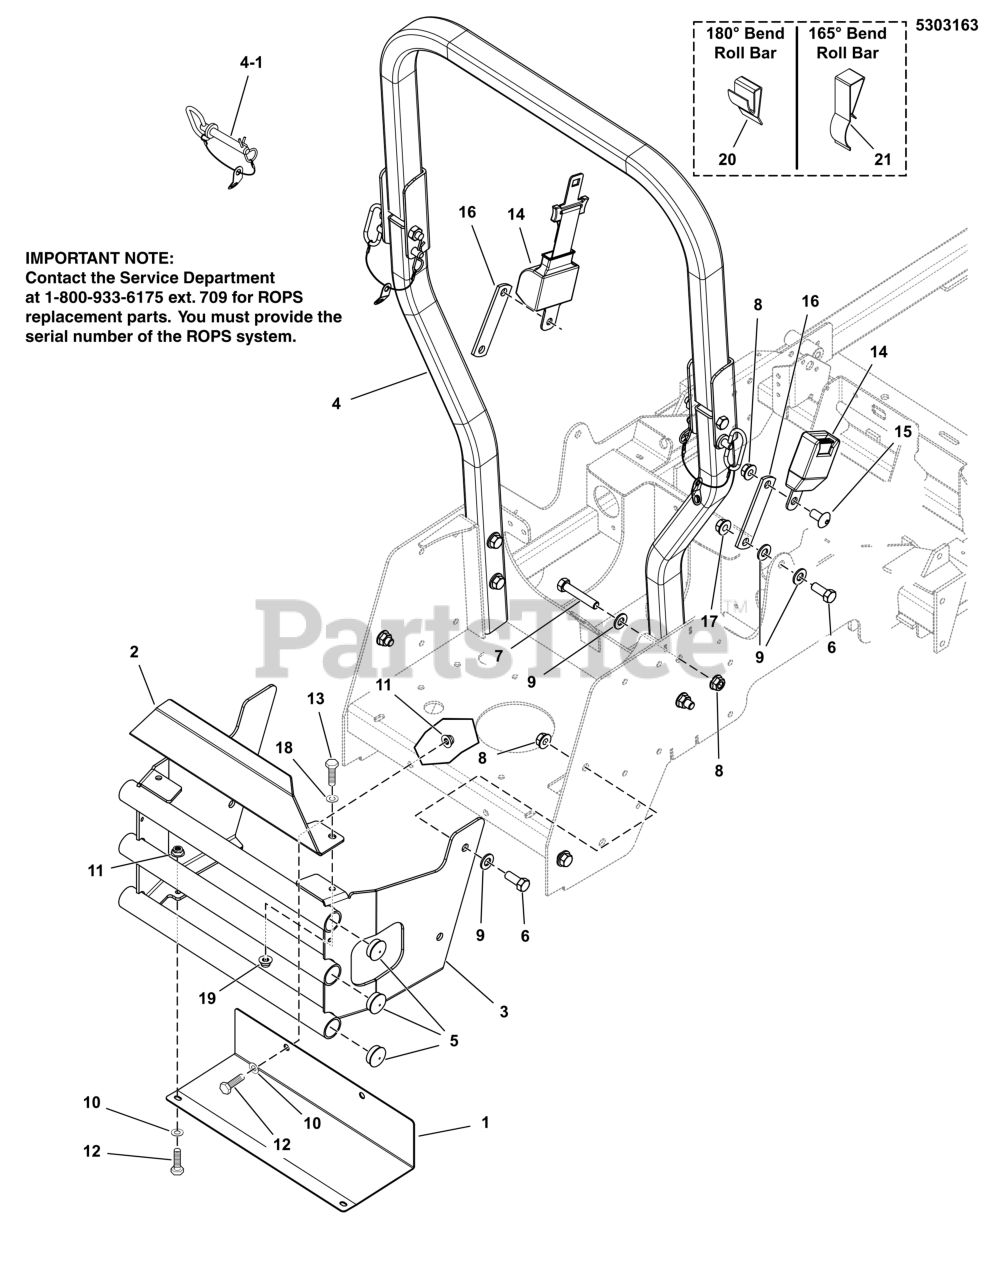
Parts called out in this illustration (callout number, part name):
1	PLATE, HEAT SHIELD, IS700 - BLK
2	PLATE, CARB PROTECTOR - RED
3	WELD, BUMPER - IS700 - RED
4	ROPS (Call 1-800-933-6175 ext. 2193 if replacing a ROPS)
4-1	PIN, HITCH, .50 X 3.2
5	PLUG, PANEL, 1.25 - BLACK
6	BOLT, 1/2-13 X 1-1/4 GD5 CZ
7	BOLT, 1/2-13 X 2-3/4 GD5 CZ
8	NUT, Hex Flange, Nylock, 1/2-13
9	WASHER, 1/2 SAE
10	WASHER, 5/16" SAE
11	NUT, 5/16-18 HEX NYLOCK FLANGE
12	BOLT, 5/16-18 X 3/4 GD5
13	BOLT, 3/8-16 X 1" GD5 CZ
14	SEAT BELT, RETRACTING - ASSM
15	SCREW, 1/2-13 X 1.00, SHCS
16	PLATE, SEAT BELT ANCHOR - BLK
17	NUT, 1/2-13 HEX NYLON LOCK
18	WASHER, 3/8 SAE
19	NUT, 3/8-16 HEX NYLOCK FLANGE
20	ANTI-RATTLE SPRING, FEMCO #230328972 (SV)
21	ANTI-RATTLE SPRING, ROPS, 165 DEGREE (SV)
